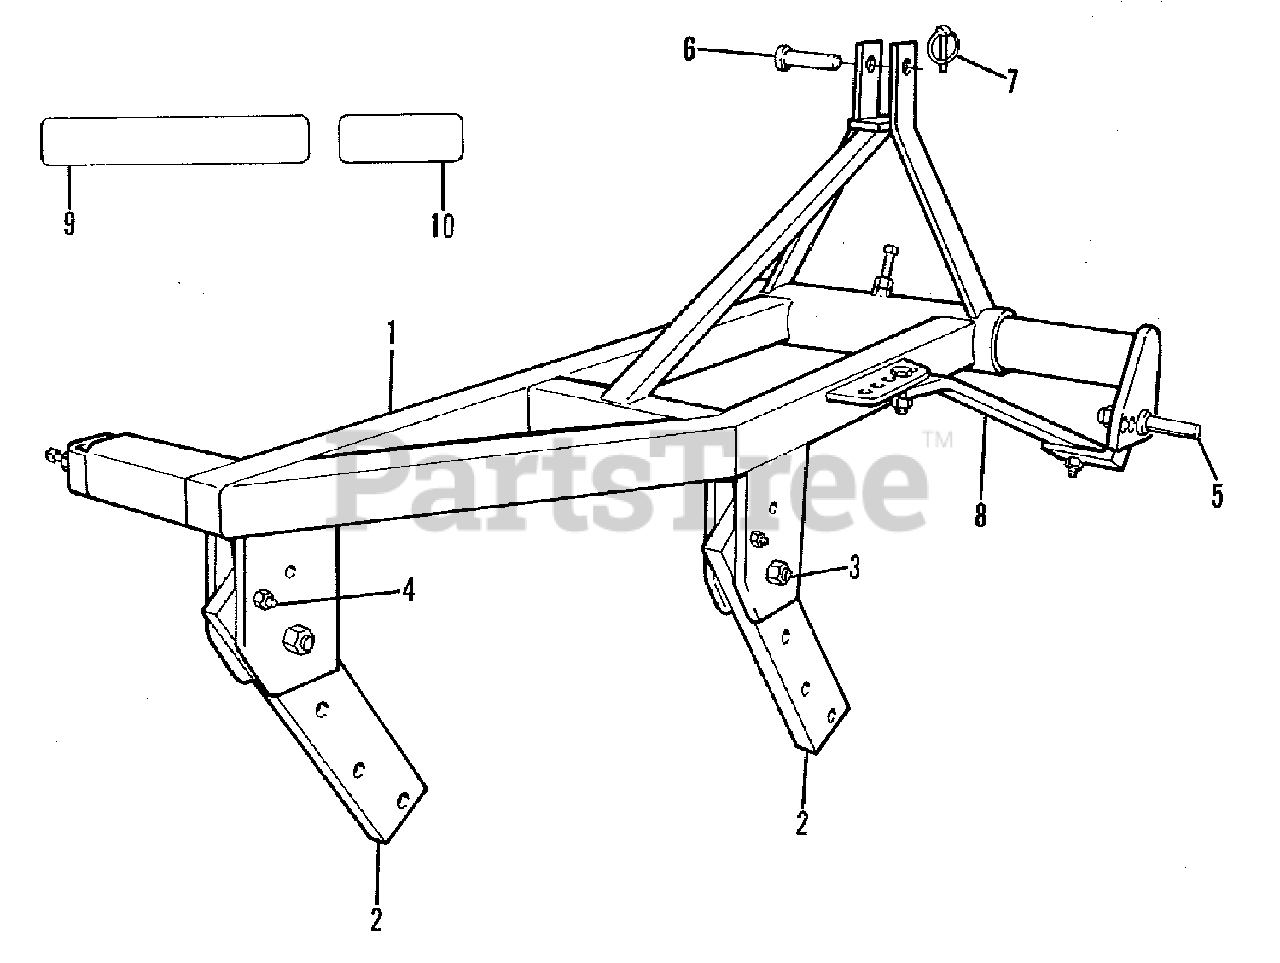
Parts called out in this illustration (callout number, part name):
1	FRAME ASSEMBLY
1	SETSCREW, Square Head, Cup Point, 5/8NC x 1-1/4
2	CAPSCREW, 5/8NC x 3
2	LOCKWASHER, 5/8
3	CAPSCREW, Beam Pivot, 3/4NC x 3
4	CAPSCREW, Beam Shear, 1/2NC x 3
4	LOCKWASHER, 1/2
5	PIN, Link (Cat. l)
5	LOCKWASHER, 7/8
6	PIN, Hitch, Upper
8	BAR, Adjusting
8	CAPSCREW, 7/16NC x 3
8	LOCKWASHER, 7/16
8	NUT, 7/16NC
9	DECAL (Allis-Chalmers)
10	DECAL (42 Model Identification)
